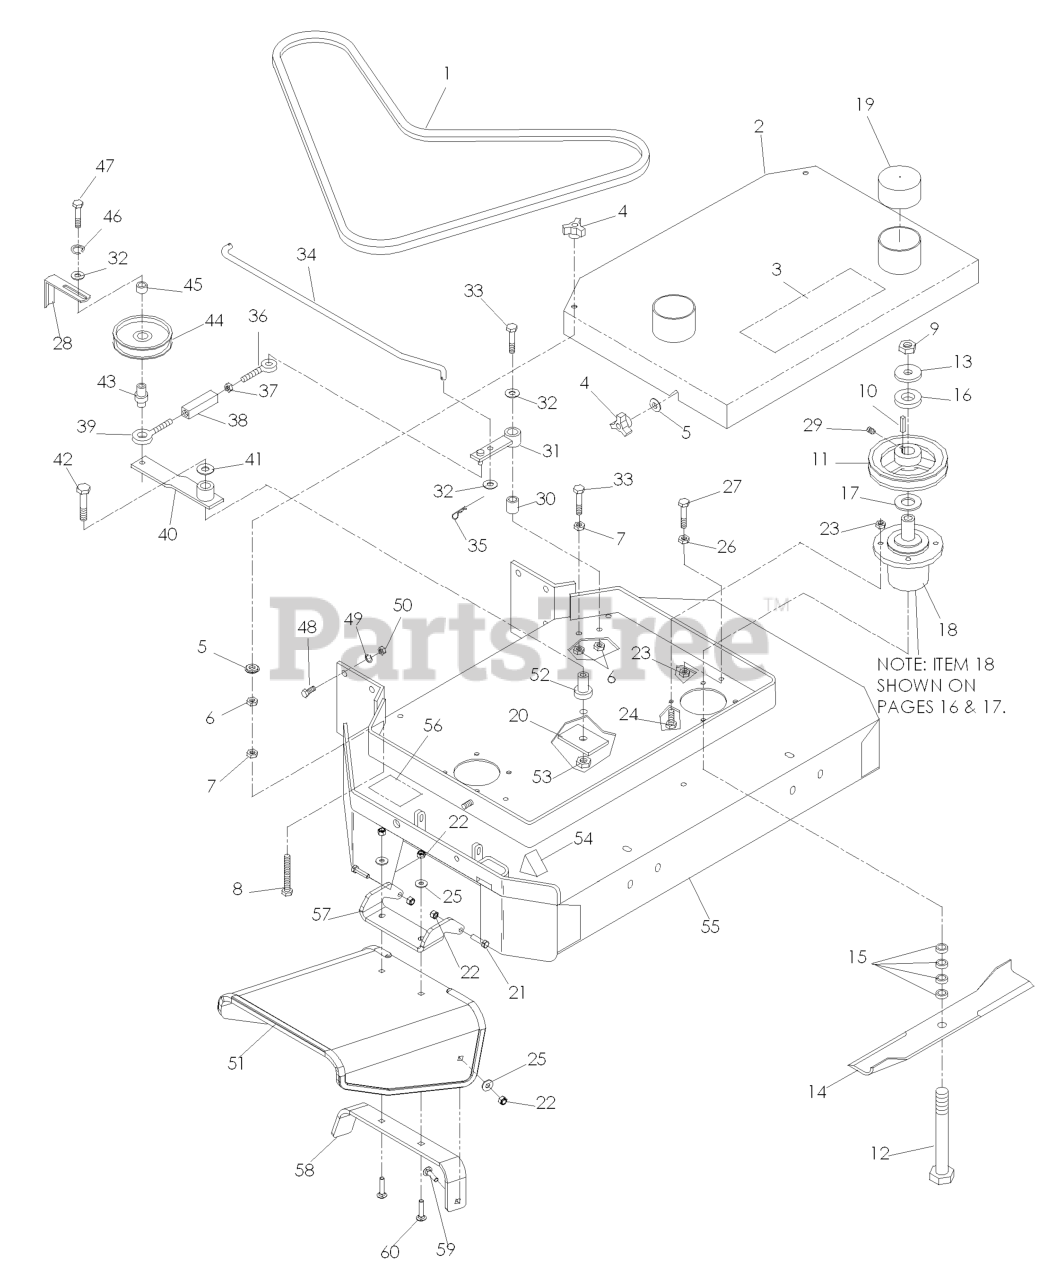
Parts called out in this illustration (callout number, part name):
1	BELT, DECK, 36"
2	BELT SHIELD ORANGE 36"
3	DECAL, HUSQ 12" BLUE
4	KNOB, THREE PRONG
5	WASHER, 3/8 SEALING
6	NUT 3/8C CENTERBLOCK
7	NUT 3/8C WHIZ
8	TAPBOLT 3/8C X 4 1/2
9	NUT 5/8F HEX
10	KEY 1/4 SQ X 1 1/8
11	PULLEY W/SETSCREWS
12	HCS 5/8F X 8 1/2
13	WASHER, SUPPORT
14	BLADE OEM 18"
15	BLADE SPACERS
17	MACHINERY BUSHING 10 GA.
18	HOUSING ASSEMBLY
21	HCS 5/16C X 1 1/4
22	NUT 5/16 NYLOC
23	NUT 5/16C CENTERLOCK
24	HCS 5/16C X 1
25	WASHER 5/16 FLAT
26	NUT 5/16C WHIZ
27	HCS 5/16 X 3
29	SET SCREW 5/16 NYLOC
30	BUSHING, SLEEVE
31	ENGAGEMENT ARM
32	WASHER 3/8 FLAT
33	HCS 3/8C X 2 1/4
34	BLADE ROD 36"
35	HAIRPIN #2
36	EYEBOLT, RH
37	NUT 5/16C HEX
38	TURNBUCKLE
39	EYEBOLT, LH
40	ARM WELDMENT
41	WASHER 1/2 FLAT
42	HCS 1/2C X 2 3/4
43	EYEBOLT PIVOT
44	IDLER PULLEY
46	SLW 3/8 STD
47	HCS 3/8C X 2 1/2
48	HCS 7/16C X 1 1/2
49	WASHER 7/16 LOCK
50	NUT 7/16C HEX
51	CHUTE, RUBBER DISCHARGE WB
52	IDLER SPINDLE
53	NUT 1/2-13 HEX NYLOC ZD
54	DECAL, CPSC
55	DECK W/DECALS 36"
56	DECAL, EURO SEVERING
57	PIVOT BRACKET - CHUTE
58	BRKT, REINF-CHUTE WB
59	BOLT, CARRIAGE 5/16X1-1/4
60	RHSNB 5/16-18 X 1-1/2 GR 5 ZD
